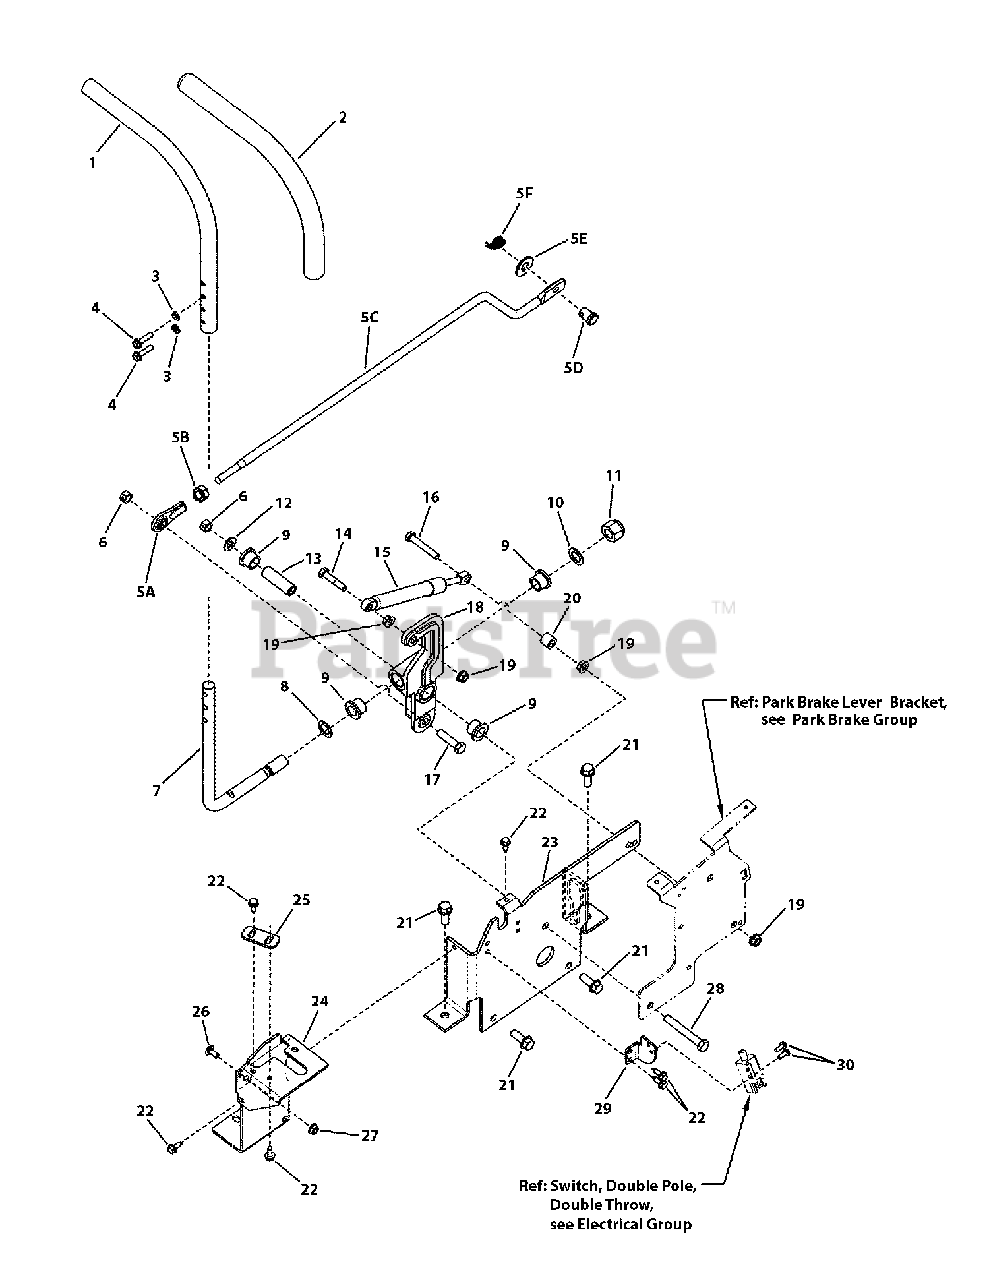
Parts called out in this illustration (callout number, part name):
1	HANDLE
2	GRIP, Handle
3	LOCKWASHER, 1/4" Spring, YZ
4	SCREW, 1/4-20 x 1" Hex Head Cap, GR 5, BZ
5A	ROD END, (3/8-24 thread)
5B	NUT, 3/8-24 Hex, GR B, YZ
5C	ROD, Link Foward/Reverse (3/8-24 thread)
5D	PIN, 7/16 x 1" Clevis
5E	WASHER, 7/16" Flat
5F	COTTER PIN, 1/2 Self, YZ
6	NUT, 3/8-16 Hex Center Lock, YZ
7	ROD, Handle R.H.
8	WASHER, .64 x .99 x .05 Flat, YZ
10	WASHER, 5/8 ID x 1.00 OD x .065 Nylon
11	NUT, 5/8-18 Hex Nyloc, YZ
12	WASHER, 3/8" Flat (SAE)
13	SPACER, Sleeve, RZT
14	SCREW, 5/16-18 x 1-1/2 Hex Head Cap, YZ
15	DAMPENER, Control
16	SCREW, 5/16-18 x 2" Hex Head Cap, GR 5, YZ
17	SCREW, 3/8-16 x 1-1/2 Hex Head Cap, GR 5, YZ
18	ARM, Die Cast Aluminum
19	NUT, 5/16-18 Hex Flange Lock, GR 5, YZ
20	SPACER
21	SCREW, 3/8-16 x 1" Hex Washer Self-Tap
22	SCREW, 1/4-20 x 3/4" Hex Washer Self-Tap, Black
23	CONTROL BRACKET, LH
24	BRACKET, Guide, Stick, Control, LH
25	PLATE, Foward/Reverse Adjust
26	BOLT, 1/4-20 x 5/8" Round Head Short Square Neck, GR 5, YZ
27	NUT, 1/4-20 Hex Flange Lock, Black
28	SCREW, 3/8-16 x 3-1/4" Hex Head Cap, GR 5
29	BRACKET, Switch
30	SCREW, #10-24 x 1/2" Hex Washer Self-Tap, Torx
